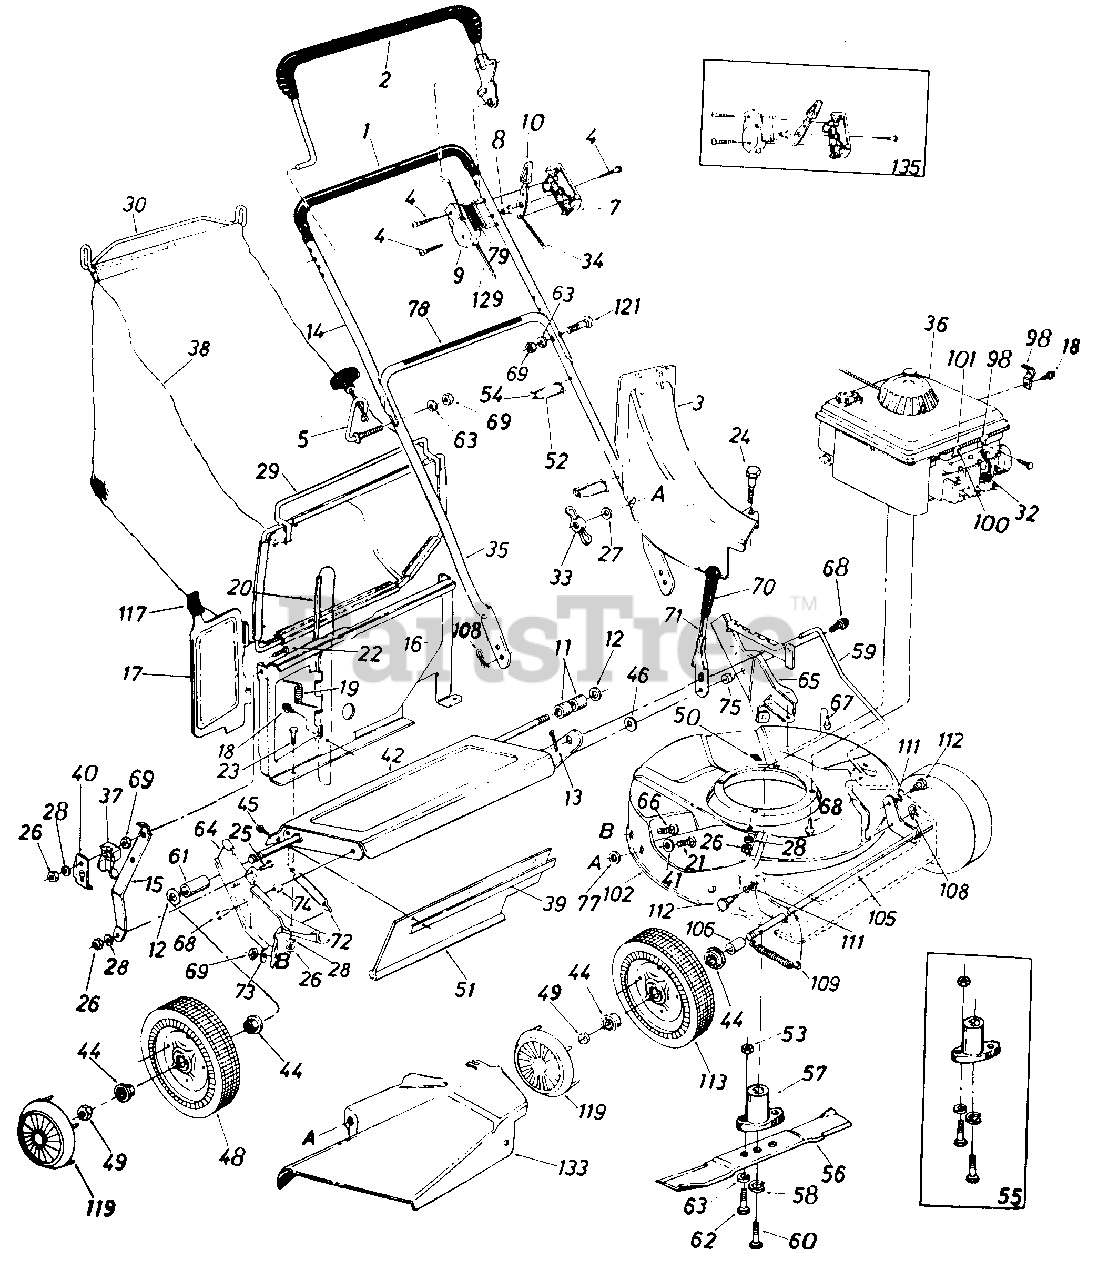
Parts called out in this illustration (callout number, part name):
1	Grip
2	Control Handle Ass'y. L.H.
3	Top Discharge Chute Ass'y.
4	Truss Mach. Scr. #12 x 1.50" Lg.
5	Rope Guide Bolt
7	Control Panel Half
8	Control Disc Pin
9	Clutch Panel Half
10	Throttle Control Lever
11	Spacer .526" I.D. x .690" O.D. x .640" Lg.
12	Fl-Wash. .510" I.D. x .75
13	Cotter Pin 3/32" Dia. x .75"*
14	Upper Handle Chrome
15	Panel Support Brkt.
16	Top Catcher Panel
17	Top Door
18	Hex B-Tap Scr. #10 x .38"
19	Torsion Spring
21	Carriage Bolt 1/4-20 x .62"*
22	Truss Mach. Scr. 1/4-20 x 1.0" Lg.
23	Hex Bolt 1/4-20 x .50" Lg.
24	Shoulder Bolt .312 Dia. x .18 Lg. Special
25	Hex Bolt 1/4-20 x .62" Lg*
26	Hex Nut 1/4-20 Thd*
27	Fl-Wash. .280" I.D. x .620"
28	L-Wash. 1/4" I.D*
29	Front Grass Catcher Frame
30	Grass Catcher Handle
32	Spark Plug Insulator
34	Throttle Control Wire 58"
35	Lower Handle Chrome
36	Engine
37	Rope Guide Half
38	21" Top Discharge Grass Bag
39	Retaining Strip
40	Rope Retainer Spring Clip
41	Fl-Wash. .344" I.D. x .62"
42	Rear Axle Ass'y.
44	Flange Ball Bearing 1/2" I.D.
45	Hex AB-Tap Scr. 1/4 x .62"
46	Fl-Wash. .38" I.D. x 1.0"
48	Rear Wheel Ass'y. Comp. 8 x 1.75
49	Hex L-Nut 1/2-20 Thd.
51	Rear Flap 3.75" x 17.30" Lg.
53	Hex Nut 5/16-24 Thd.
54	Cable Anchor
55	Blade Adapter Kit
57	Blade Adapter
58	L-Wash, 3/8" I.D. H.D.
59	Height Adj. Rod. 19.42" Lg.
60	Hex Bolt 3/8-24 x 2.25" Lg. (Grade 5)
61	Spacer .513 x .703 x. 69"
62	Hex Bolt 5/16-24 x 1.00" Lg. (Grade 5)
63	L-Wash. 5/16" I.D*
64	R.H. Handle Wheel Brkt. Ass'y.
65	L.H. Handle Wheel Brkt. Ass'y.
66	Carriage Bolt 5/16-18 x .62"*
67	Hex Wash. Hd. B-Tap Scr. 5/16-18
68	Hex Wash. Hd. TT-Tap Scr. 3/8-16
69	Hex Nut 5/16-18 Thd.
71	Height Adj. Lever
72	Extension Spring .50" O.D. x 3.80" Lg.
73	Bell-Wash 5/16" I.D.
74	Spacer .385" I.D. x .502" O.D. x .270" Lg.
75	Shld. Spacer .500" Dia. x .100
77	Bolt Retainer 1/4 X .50" O.D.
78	Instruction Label
79	Control Label
98	Casing Clamp
100	Hex B-Tap Scr. #10 x .62"
101	Casing Clamp
102	21" Deck Ass'y.
105	Front Axle Ass'y.
106	Sleeve .526" I.D. x .690" 0. D . x .880" Lg.
108	Intern. Cotter Pin 5/16" Dia.
109	Extension Spring .50" O.D. x 3.20" Lg.
111	Intern. L-Wash. 3/8 I.D*
112	Shld. Bolt .623" Dia. x .425
113	Front-Wheel Ass'y. Comp. 7 x 1.50
119	Hub Cap Plastic Black
121	Curved Carr. Bolt 5/16-18 x 1.38" Lg.
129	Control Cable 43" Lg.
133	Side Chute Deflector Ass'y.
135	Kit Control Housing Comp.
8112-000-6	Hardware Pack
